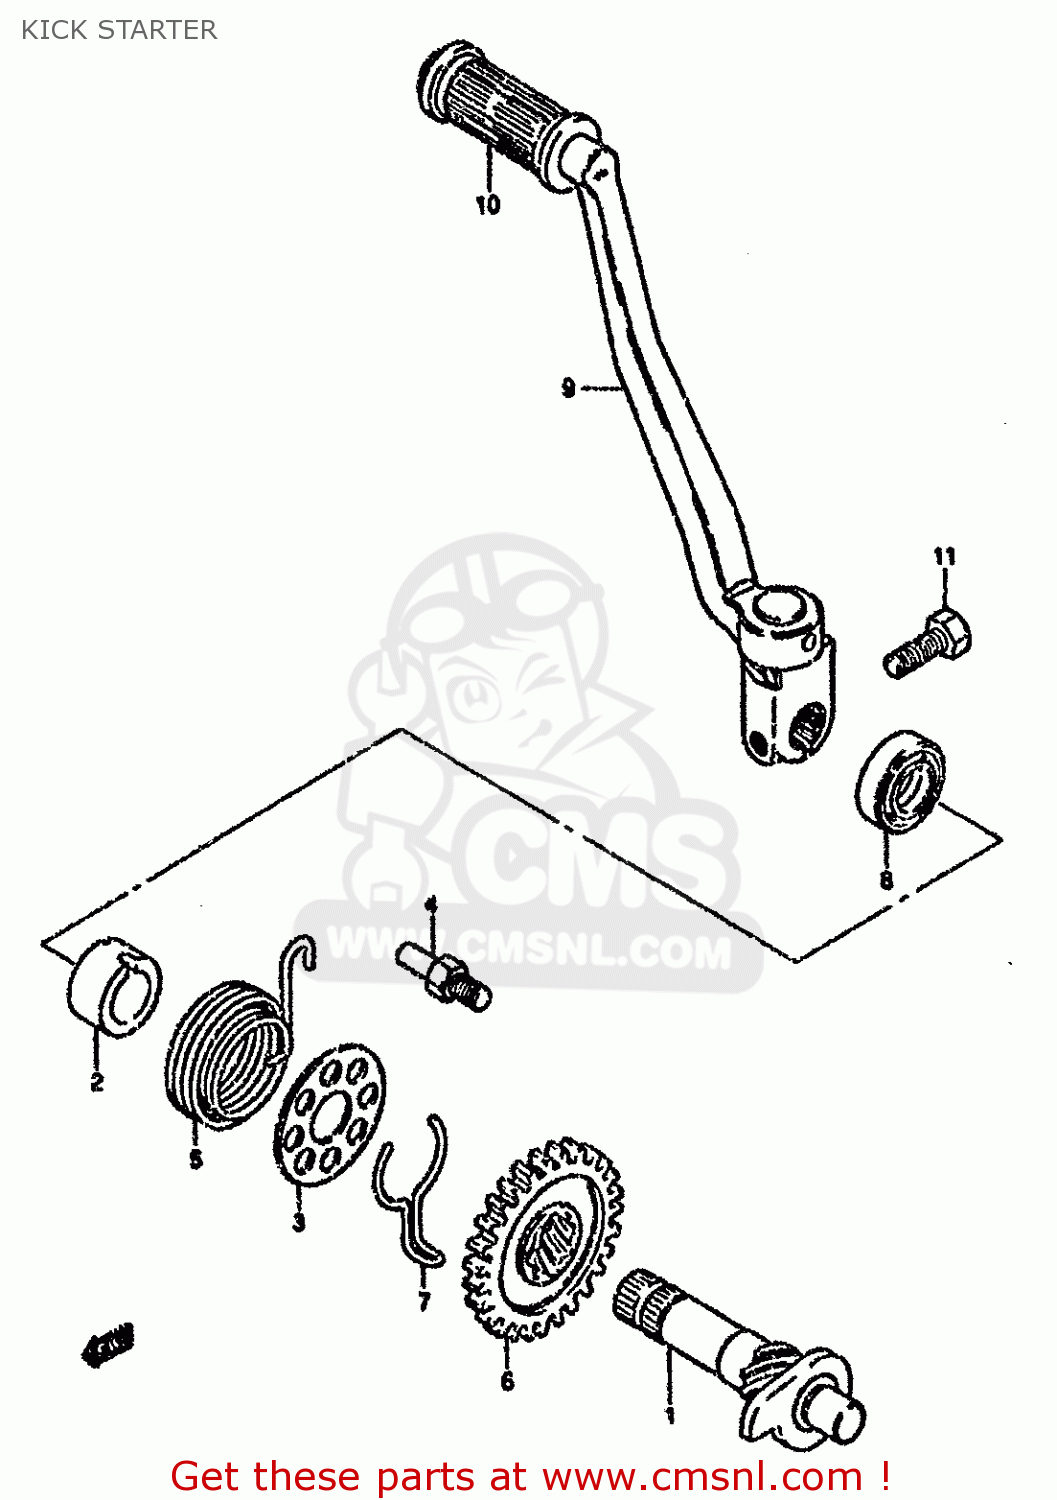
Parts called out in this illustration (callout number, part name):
1	SHAFT,KICK STARTER
2	GUIDE,KICK STARTER SFT SPRING
3	HOLDER,KICK STARTER SHAFT SPR
4	BOLT,KICK START SHAFT SPR HOOK
5	SPRING
6	GEAR, KICK STARTER DRV.
7	SPRING,KICK STARTER RETAINER
8	SEAL,OIL(14X24X6)
9	LEVER ASSY,KICK STARTER
10	RUBBER,KICK STARTER PEDAL
11	BOLT
